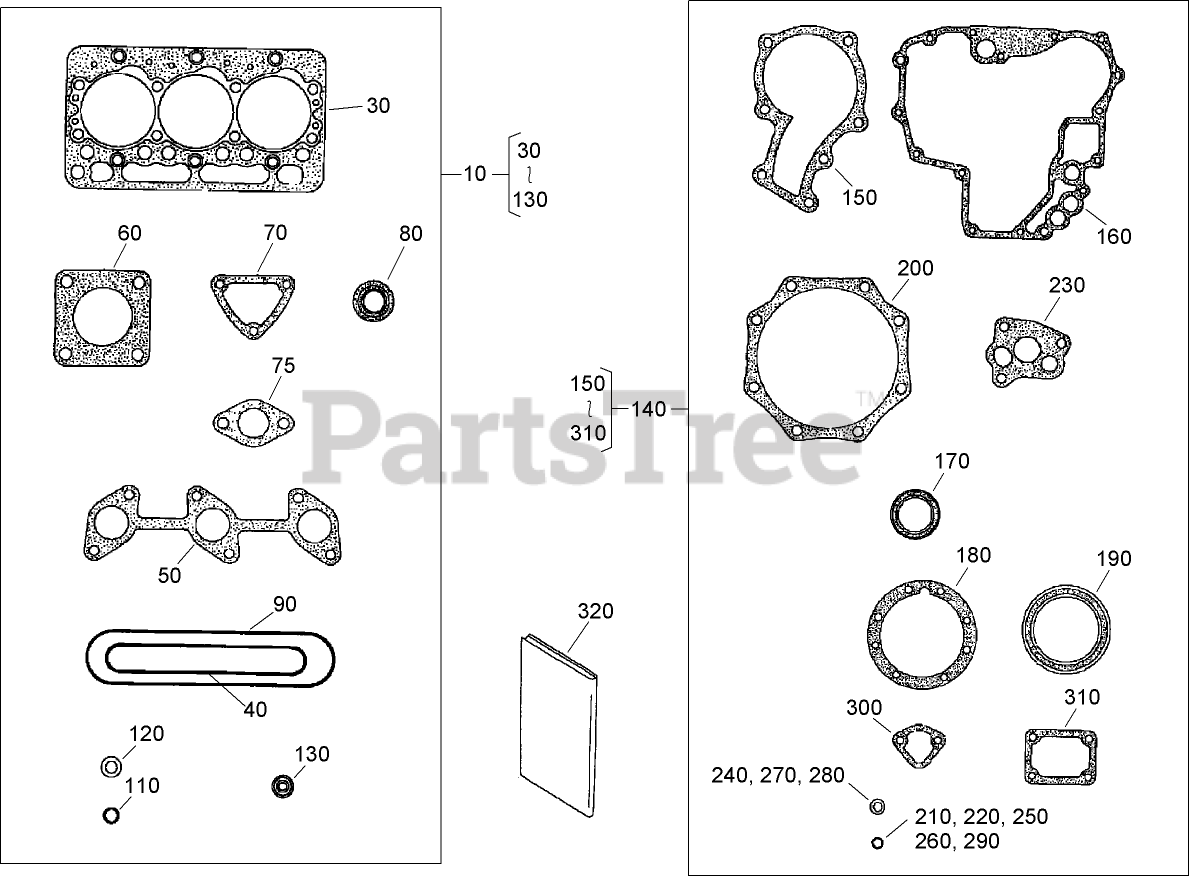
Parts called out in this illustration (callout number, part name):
10	UPPER GASKET KIT
30	GASKET-HEAD, CYLINDER
40	GASKET-MANIFOLD, INTAKE
50	GASKET-MANIFOLD, EXHAUST
60	GASKET-MUFFLER
70	GASKET-FLANGE, WATER
75	GASKET-THERMOSTAT
80	SEAL-STEM, VALVE
90	GASKET-COVER, HEAD
110	O-RING
120	GASKET
130	SEAL-HEAT
140	LOWER GASKET KIT
150	GASKET-PUMP, WATER
160	GASKET-GEARCASE
170	SEAL-OIL
180	GASKET-CASE, BEARING
190	SEAL-OIL
200	GASKET-COVER, CASE
210	O-RING
220	O-RING
230	GASKET-PUMP, OIL
240	GASKET
250	O-RING
260	O-RING
270	GASKET
280	GASKET-PAN, OIL
290	O-RING
300	GASKET-PUMP, FUEL
310	GASKET-PLATE, CONTROL
320	MANUAL-OPERATOR
